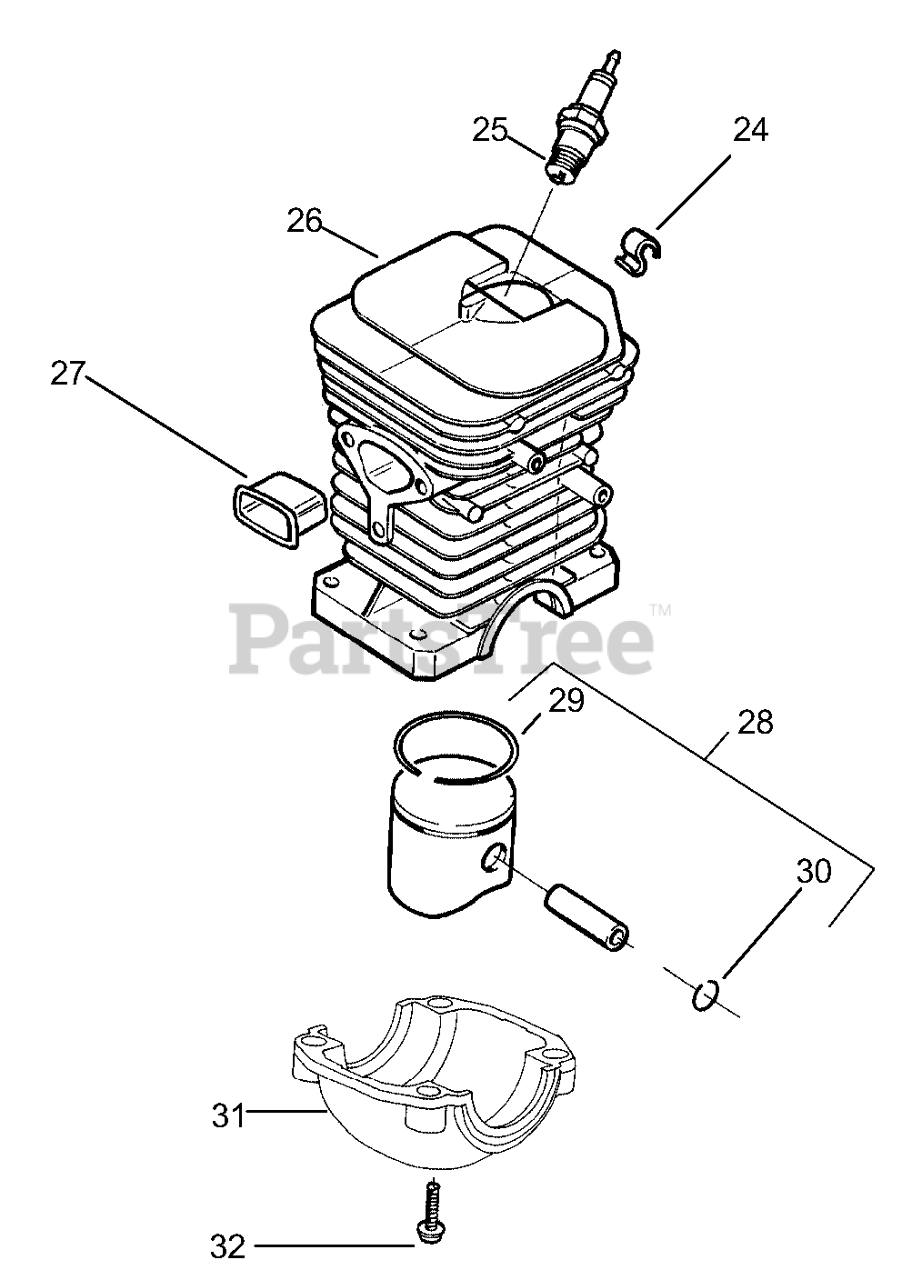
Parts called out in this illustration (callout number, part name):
24	CLIP - HIGH TENSION LE
25	Spark Plug (RCJ-7Y)
26	CYLINDER ASSY/136
27	HEAT INSULATOR
28	PISTON KIT/136
29	PISTON RING 36
30	C-CLIP,PSTN PIN 36/41
31	CAP-CRANKSHAFT
32	SCREW-M5-0.8 X 25MM(TAP)
